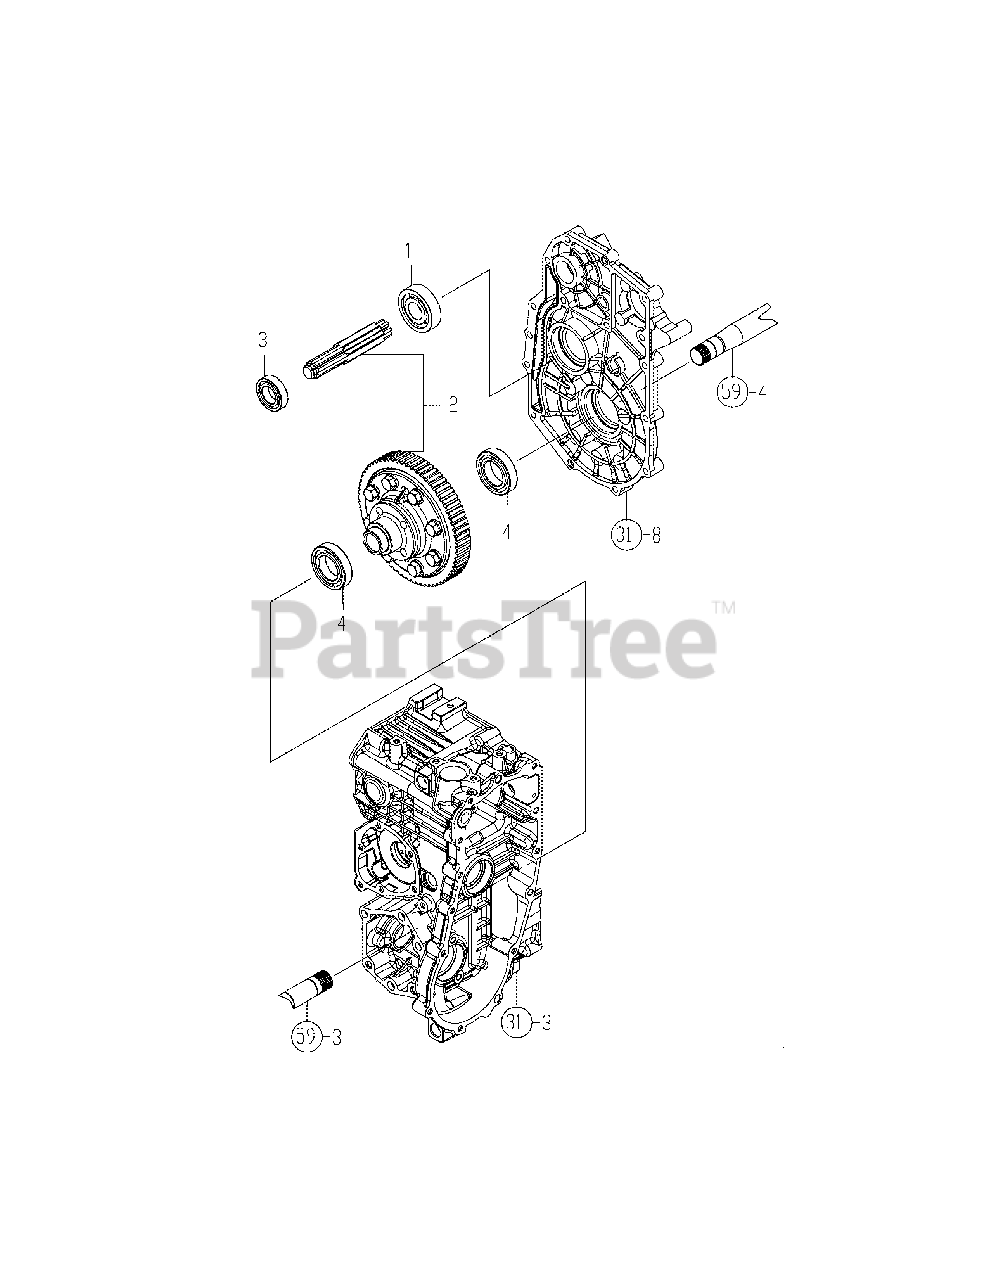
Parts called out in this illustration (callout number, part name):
1	Bearing, Tmb305
2	Gear Kit, Final
3	Bearing, 6005Sh2
4	Bearing, 6007 Ntn
